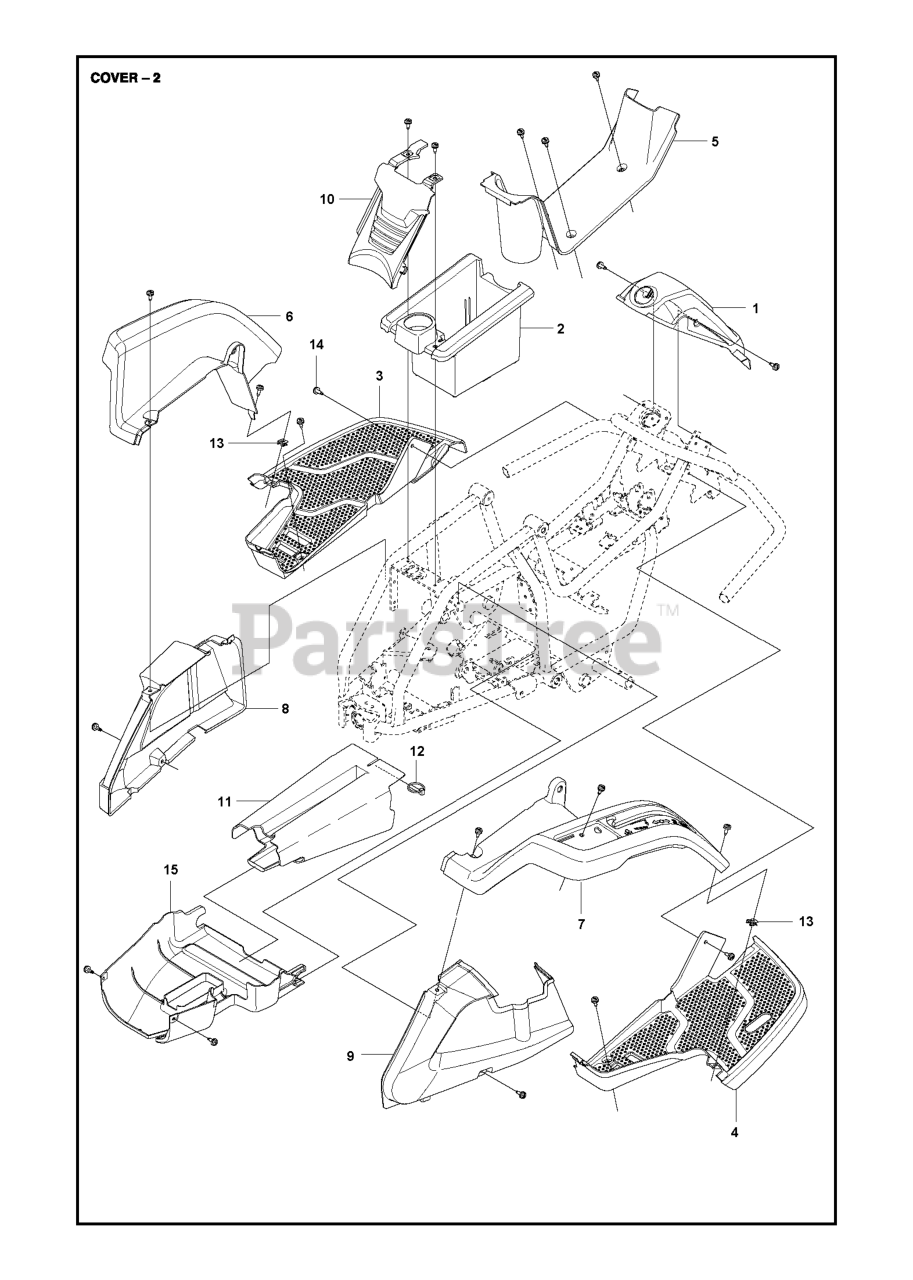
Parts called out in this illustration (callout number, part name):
2	BATTERY BOX
3	FOOT PLATE
4	FOOT PLATE
7	CONTROL PANEL
8	COVER
12	SPRINT
12	R-CLIP
